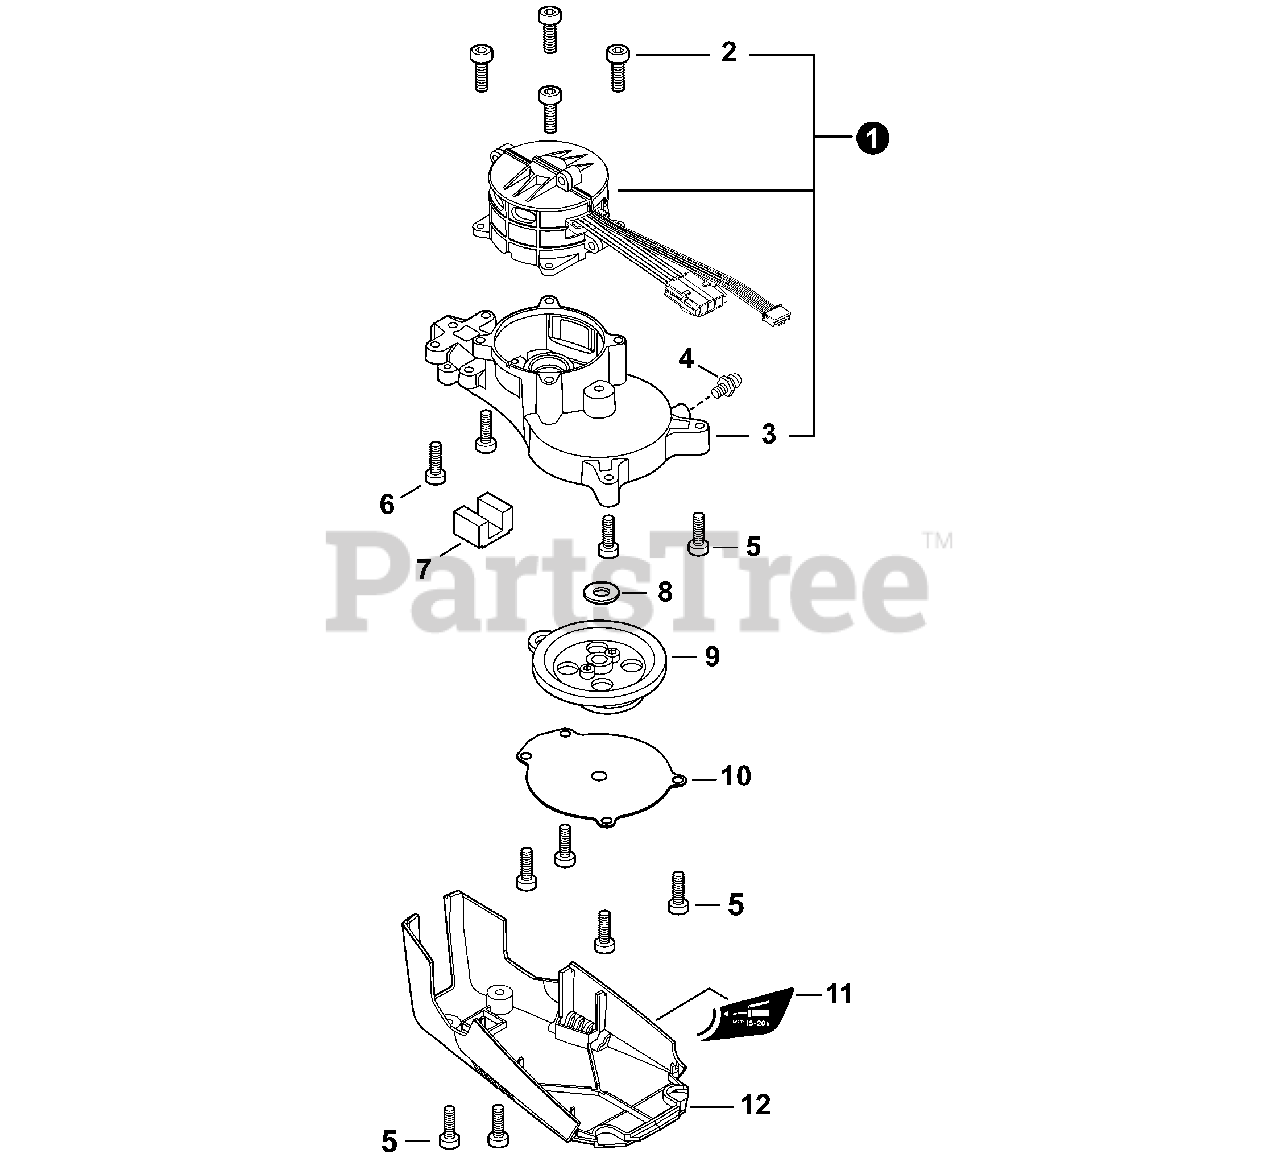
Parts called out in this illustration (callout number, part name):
1	MOTOR ASSY
2	BOLT, TORX 4×16
3	GEAR CASE ASSY
4	FITTING, GREASE
5	BOLT, TORX 5×12
6	BOLT, TORX 5×20
7	PACKING, FELT
8	WASHER 8
9	GEAR ASSY
10	PLATE, GEAR CASE
11	LABEL, GREASE
12	COVER, GEAR CASE
